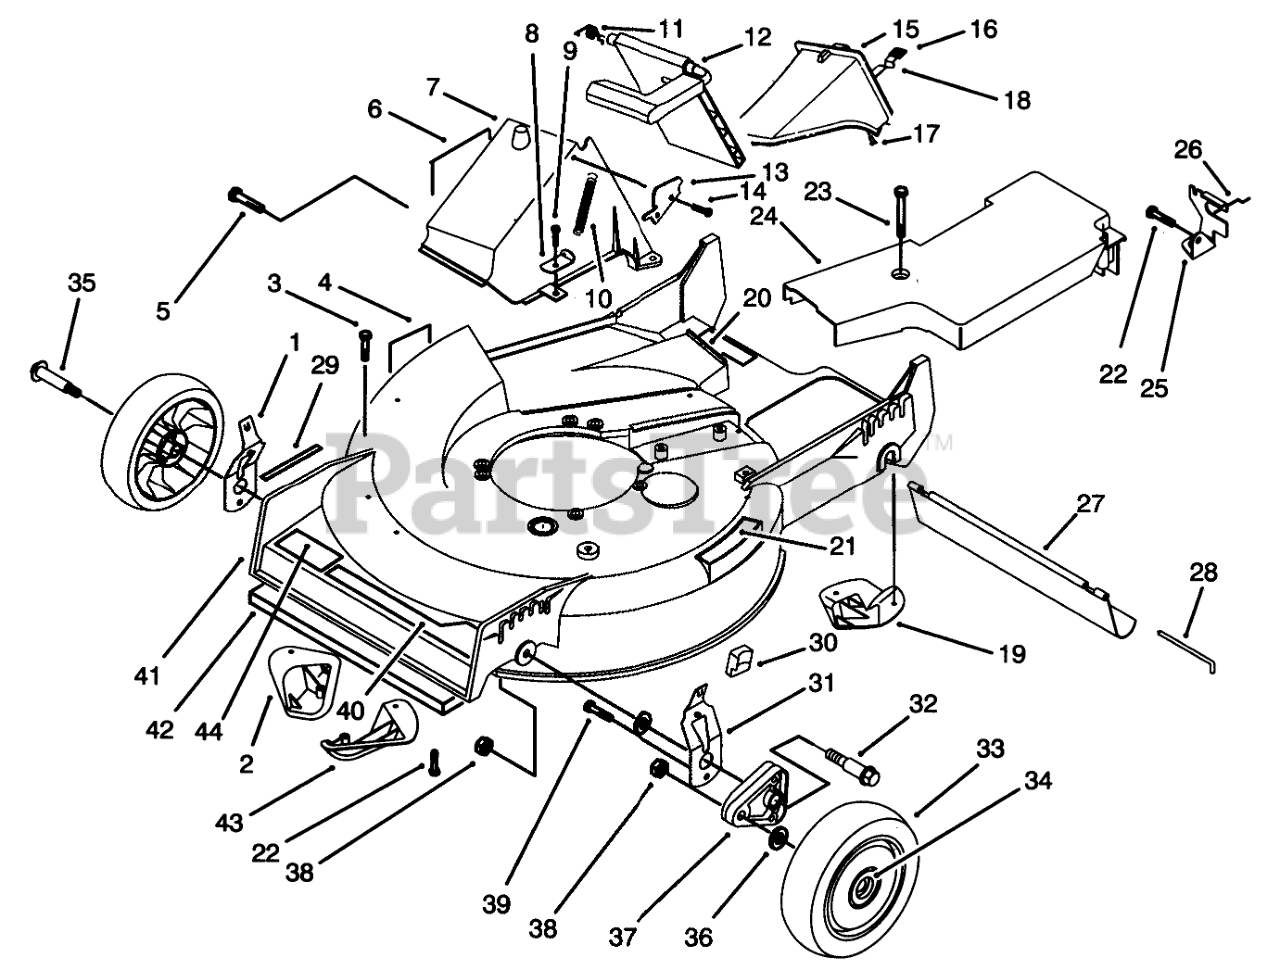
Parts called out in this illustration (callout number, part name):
1	RH SPRING ARM ASSEMBLY
2	KICKER-RH
3	SCREW-PPH
4	Decal Danger
5	SCREW AND WASHER ASM
6	DECAL - DANGER
7	Tunnel-Discharge (Incl. Ref. #6)
8	BRACKET-SPRING
9	SCREW-HWH
10	SPRING-DOOR
11	RETAINER-DOOR
12	DOOR ASSEMBLY
13	DOOR LATCH PLATE
14	SCREW-PLASTITE
15	Plug Assembly (Incl. Ref. #16-18)
16	GRIP-LATCH
17	RIVET-HEAD, FLAT
18	LATCH-PLUG, DISCHARGE
19	KICKER-REAR
20	DECAL FRENCH REGUL.
21	DECAL - STEP PAD INT'L
22	SCREW-HWHTF
23	SCREW-HHFTF
24	BELT COVER
25	Bracket-Adj. Trac
26	RETAINER-CABLE
27	SHIELD-TRAILING
28	ROD-SHIELD
29	DECAL - HOC
30	KNOB-ARM
31	LH SPRING ARM ASSEMBLY
32	SCREW-SHOULDER
33	Wheel & Tire Assembly (Incl. Ref. #34)
34	BUSHING
35	BOLT-WHEEL
36	WASHER
37	ARM-PIVOT, FRONT
38	NUT-LOCK
39	SCREW-HWH
40	DECAL - DECK
41	Housing Assembly (Incl. Ref. #2, 3, 19, 22, 29, & 43 pg. 2) (Incl. Ref. #5 & 6 pg. 3)
42	Shield-front
43	KICKER-FRONT
44	DECAL
